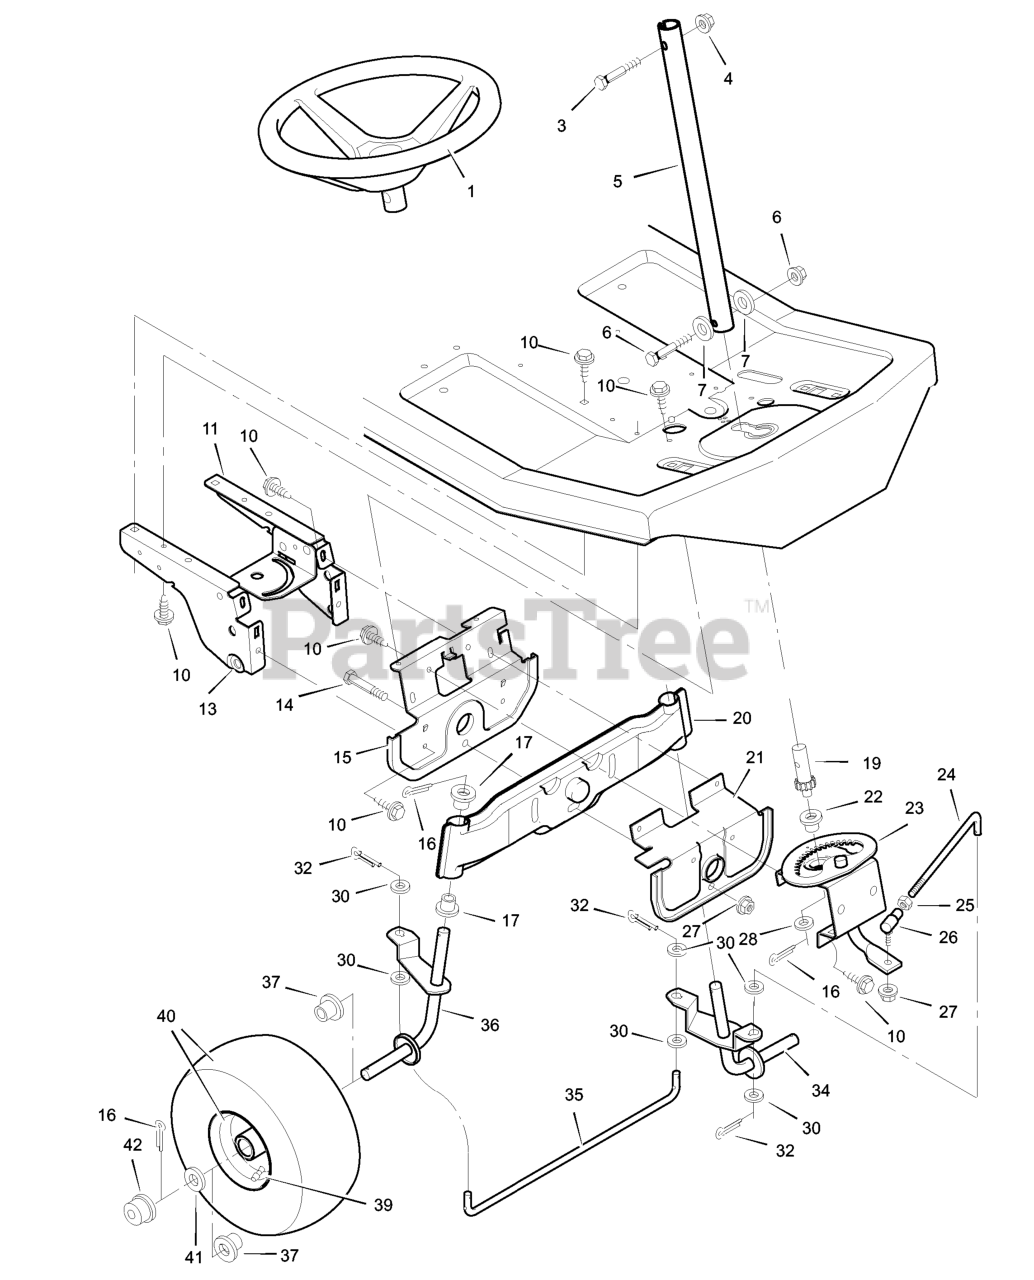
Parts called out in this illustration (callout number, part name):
1	Steering Wheel
3	Bolt, Hex
4	Locknut, Flange
5	Post, Steering
6	Nut, Hex
7	Washer
11	Plate, Left Suspension
13	Plate, Right Suspension
14	Bolt, Hex
15	Support, Front Axle
16	Pin, Cotter
17	Bearing, Spindle
19	Gear, Pinion
20	Axle Assembly, Front
21	Hanger Assembly, Front Axle
22	Bearing
23	Sector Assembly
24	Rod, Drag Link
25	Nut, Hex
26	Ball Joint, Steering
27	Locknut, Flange
32	Pin, Cotter
34	Spindle Assembly, Left
35	Rod, Tie
36	Spindle Assembly, Right
37	Bearing, Wheel
39	Valve Stem
40	Wheel & Tire Assembly
42	Cap, Hub
